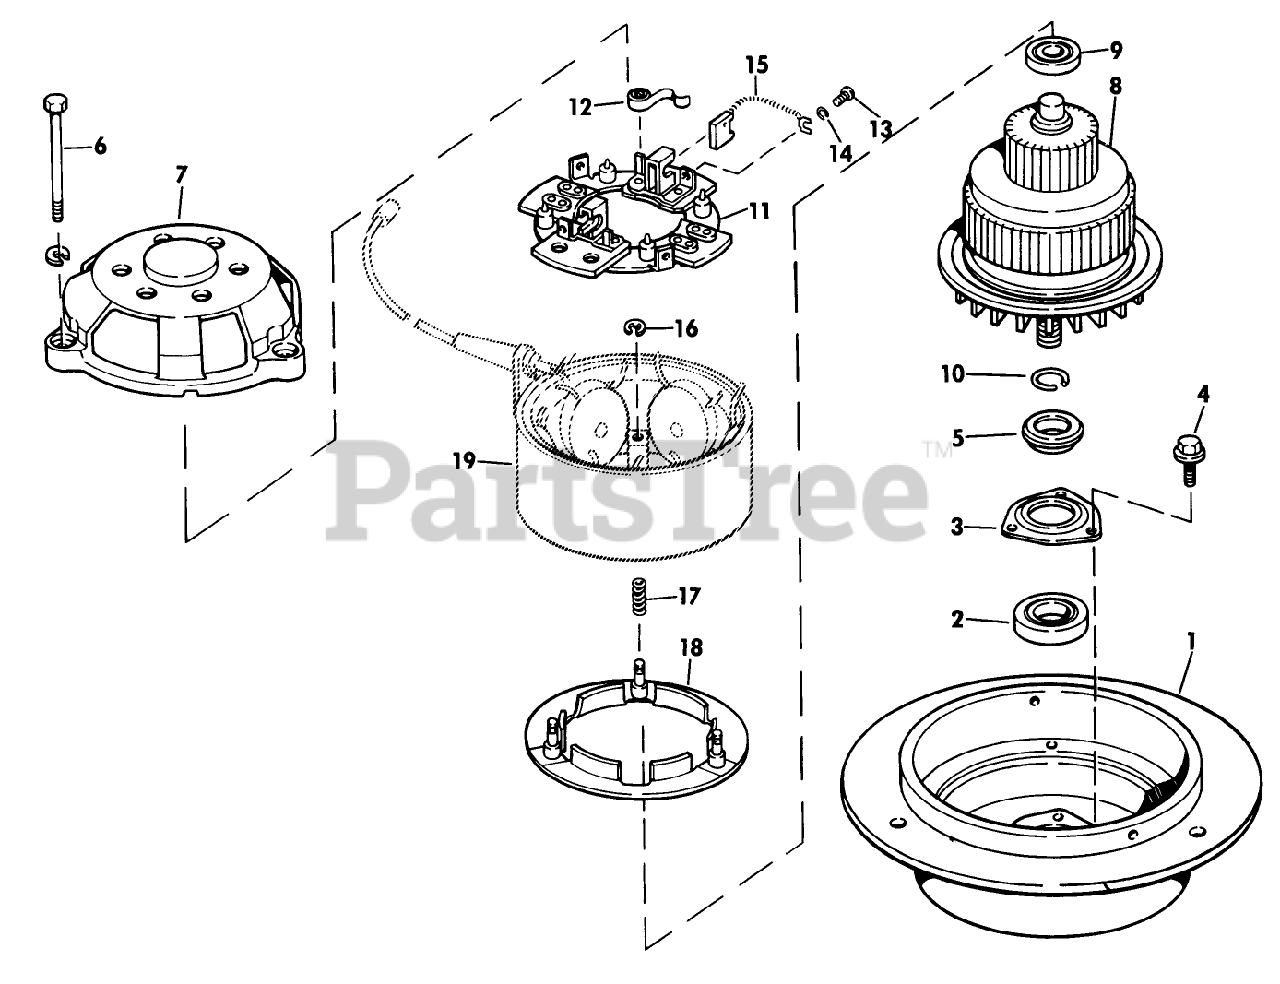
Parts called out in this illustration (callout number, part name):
1	End Bell-Motor
6	Screw-Motor Assembly
15	Brush
18	Brake Disc
19	Stator Assembly
